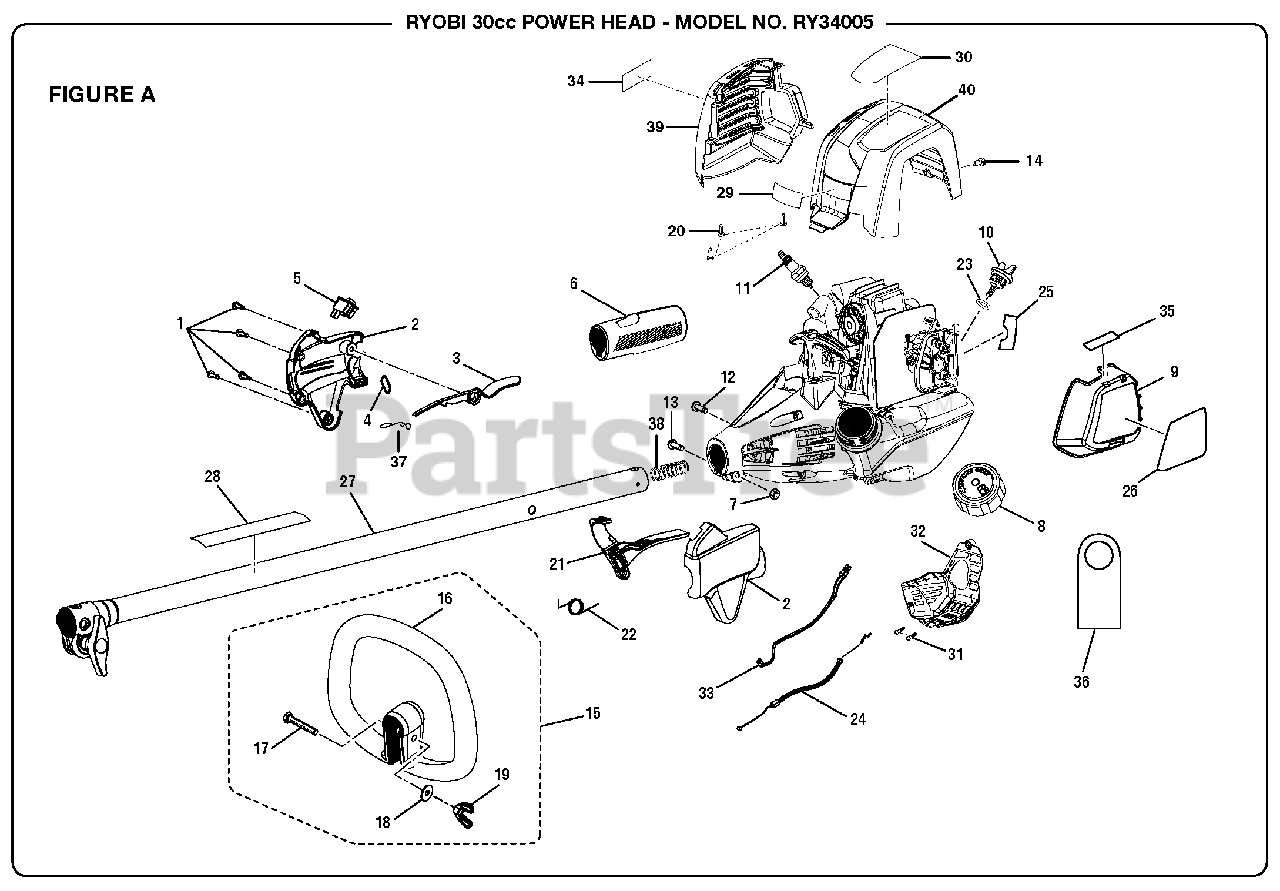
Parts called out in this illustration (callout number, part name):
1	Screw (M4 x 20 mm)
2	Control Handle Assembly
3	Trigger Lock
4	Strap Hanger
5	Switch (Momentary Contact)
6	Rear Handle
7	Hex Nut (M6.3 x 1)
8	Fuel Cap Assembly
9	Air Filter Cover
10	Oil Cap/Dipstick
11	Spark Plug (Champion RY4C)
12	Screw (#8-16 x 5/16 in.)
13	Bolt (M6 x 1 x 20 mm)
14	Screw (M4 x 11 mm)
15	Front Handle Assembly
16	Front Handle
17	Bolt (1/4-20 x 40 mm)
18	Washer (1/4 in.)
19	Wing Nut (1/4-20)
20	Screw (M4 x 12 mm)
21	Throttle Trigger
22	Throttle Trigger Spring
24	Throttle Cable
25	Hot Surface Label
26	Starting Label
27	Upper Boom Assembly
28	Warning Label
29	Logo Label
30	X430 Label
31	Screw (#6-19 x 1/2 in.)
32	CE Cover (Bottom Cover)
33	Lead Assembly
34	Combustion Warning Label
35	Choke Label
36	Oil Hang Tag
38	Compression Spring
39	Muffler Housing
40	Top Cover
